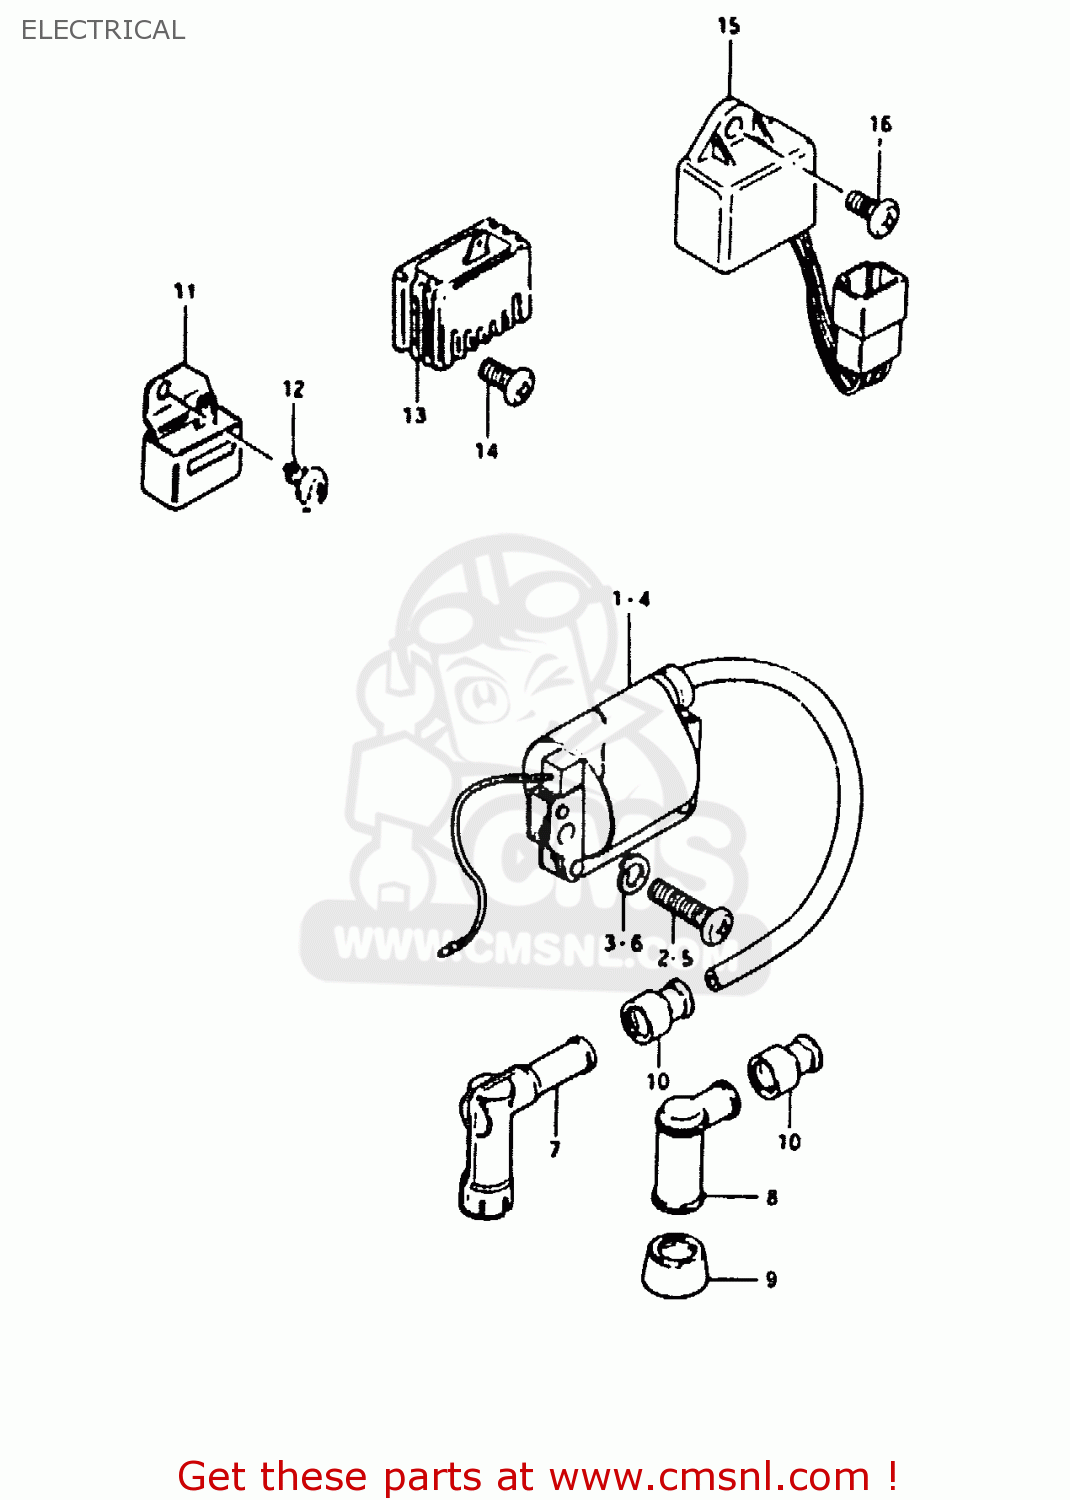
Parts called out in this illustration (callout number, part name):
1	COIL ASSEMBLY,IGNITION
2	SCREW
3	LOCK WASHER
7	CAP,SPARK PLUG
10	SEAL,SPARK PLU
11	REGULATOR ASSEMBLY
12	SCREW
